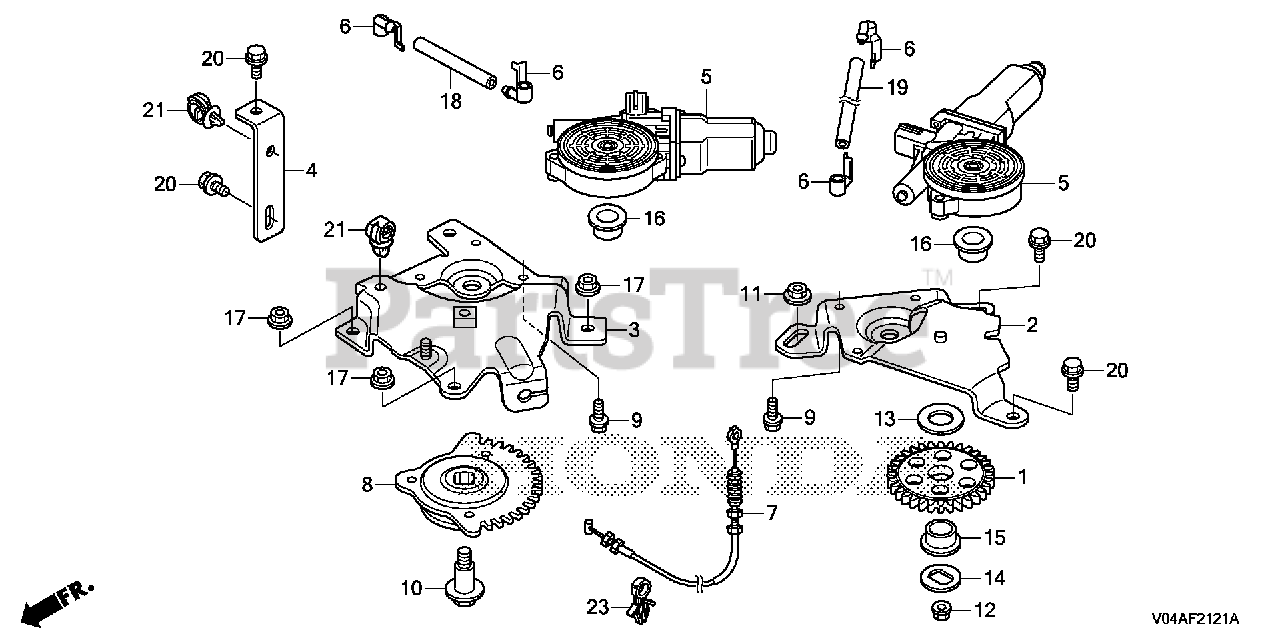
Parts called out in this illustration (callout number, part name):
1	GEAR, IDLE (32T)
2	BRACKET, CHUTE MOTOR
3	BRACKET A, CHUTE MOTOR
4	BRACKET B, CHUTE MOTOR
5	MOTOR ASSY., CHUTE
6	CAP, WATER PROTECTION
7	CABLE, CHUTE GUIDE
8	GEAR, CHUTE GUIDE MOTOR (46T)
9	SCREW, TAPPING (5X14)
10	BOLT, SHOULDER (M8)
11	NUT, FLANGE (6MM)
12	NUT, SELF-LOCK (6MM)
13	WASHER (12.5X28X1)
14	WASHER, SPECIAL
15	BUSH (12X6)
16	BUSH (10X5)
17	NUT, FLANGE (6MM)
18	BULK HOSE, VACUUM (4.5X1000) (4.5X290)
19	BULK HOSE, VACUUM (4.5X1000) (4.5X290)
20	BOLT, FLANGE (6X12) Use up to Engine SN 1543277.
21	CLIP, WIRE HARNESS (25MM)
23	CLIP, IGNITION WIRE
